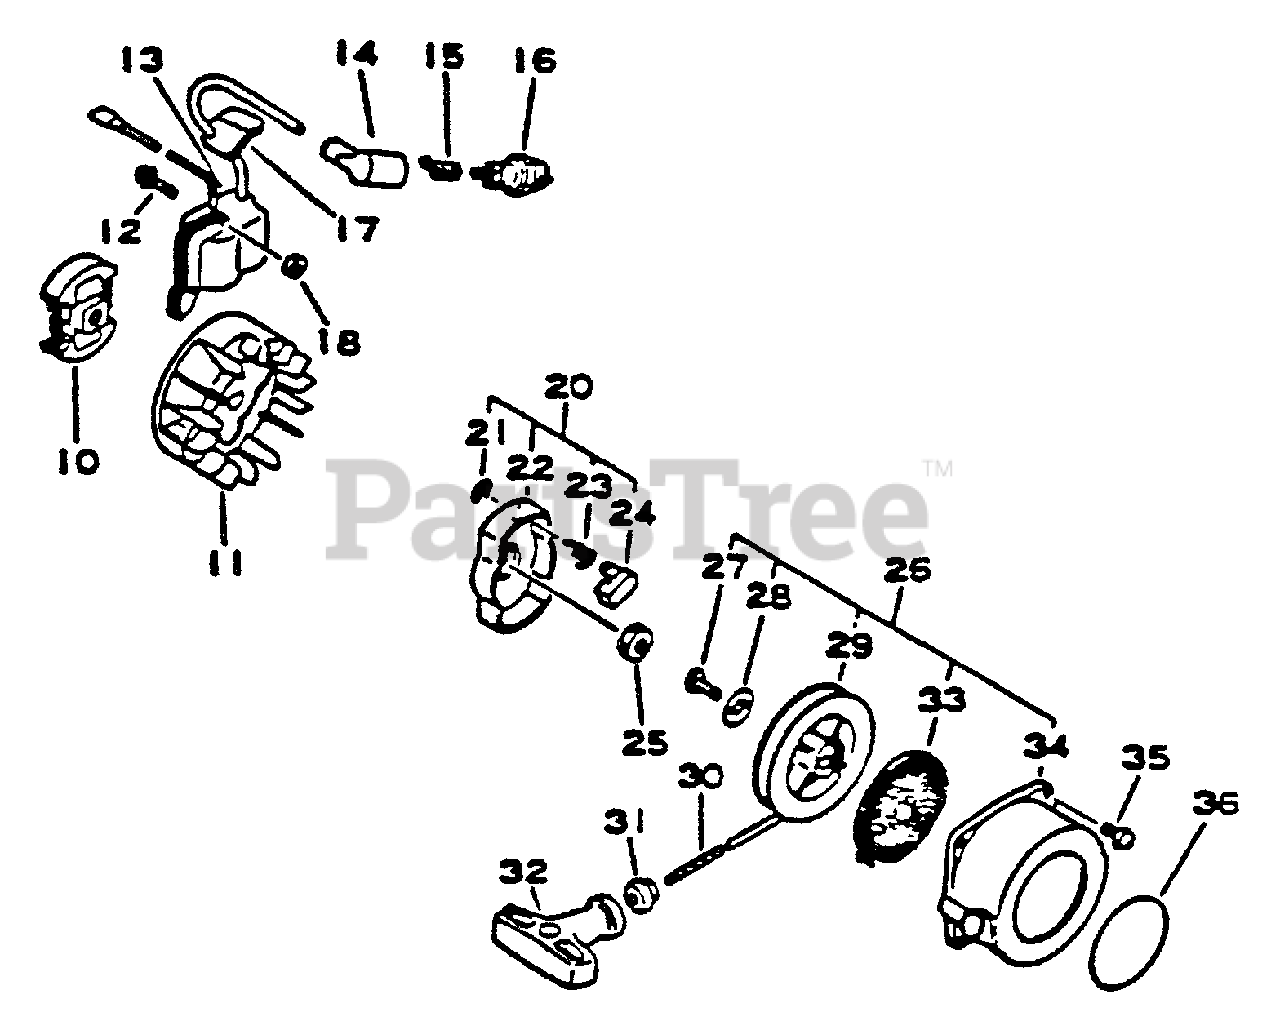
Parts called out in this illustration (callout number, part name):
10	CLUTCH ASSY
11	FLYWHEEL
12	SCREW 4×22
13	COIL, IGNITION
14	CAP, SPARK PLUG
15	TERMINAL, SPARK PLUG
16	SPARK PLUG - BPM7A
20	STARTER PAWL ASSY
21	RING, RETAINING - 6
22	CATCHER, PAWL
23	SPRING, RETURN
24	PAWL, STARTER
25	NUT 8×1.25
26	STARTER ASSY
28	WASHER
29	REEL, ROPE
30	ROPE, STARTER
31	GUIDE, ROPE
32	GRIP, STARTER
33	SPRING, RECOIL
34	CASE, RECOIL STARTER
35	SCREW 4×16
36	LABEL - ECHO
